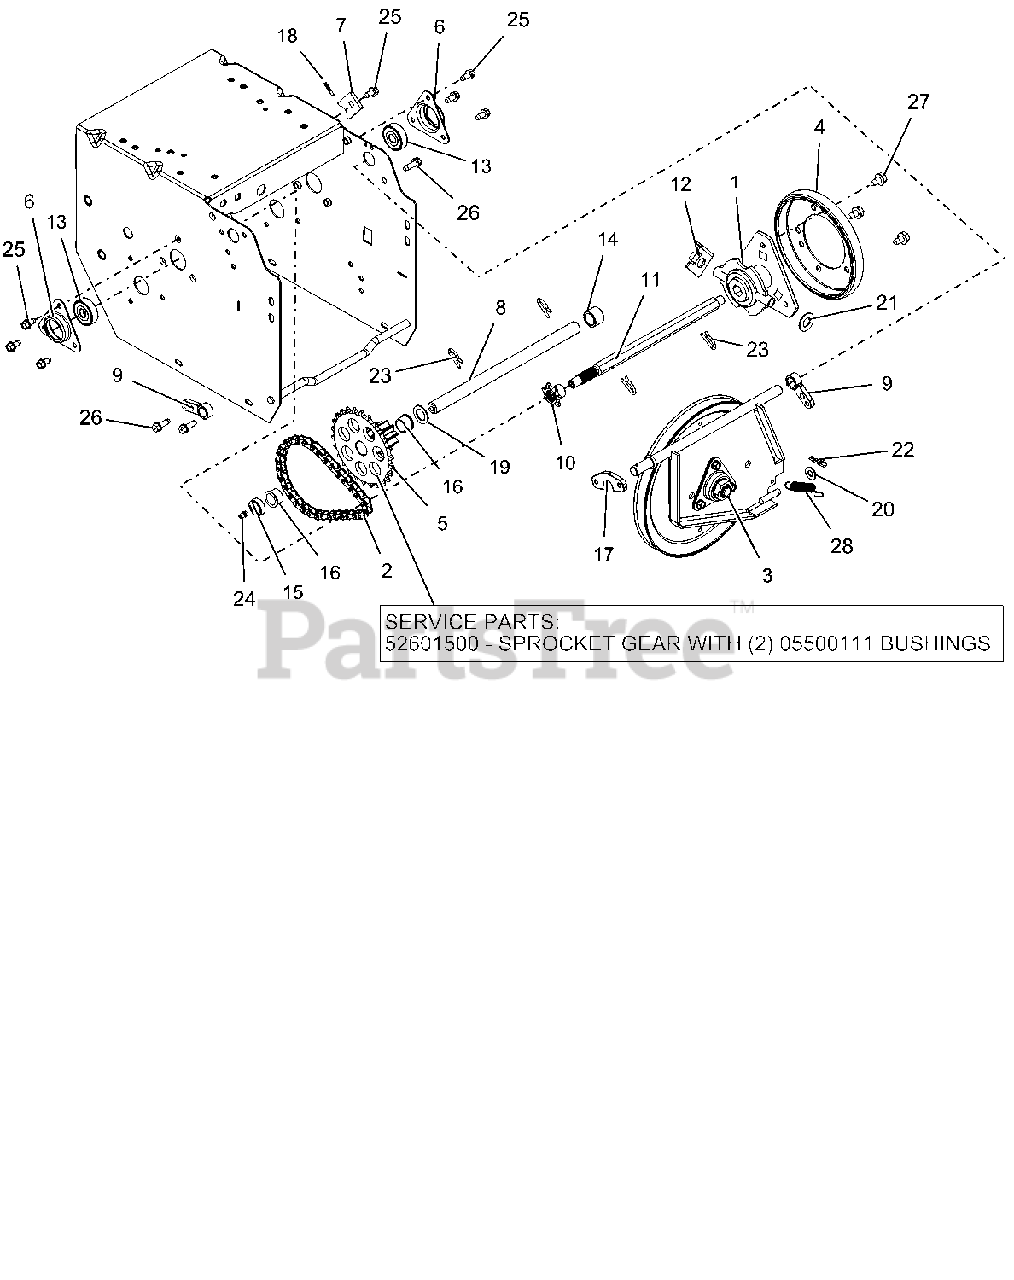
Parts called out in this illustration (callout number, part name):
1	CARRIER, DRIVE DISK
2	CHAIN - #41, 32 PITCHES
3	PLATE, SWING - ASSEMBLY
4	FRICTION, DISC
5	BSHG-FLG .625X.750X.500X.875
5	PINION & SPROCKET
5	PINION & SPROCKET W/BUSHINGS
6	FLANGE, BEARING
7	TAB, ANTI ROTATION
8	SHAFT, PINION
9	SUPPORT BUSHING, SWING GATE
10	SPROCKET, PINION 7T W/SPLINE
11	SHAFT, HEX W/SPLINE
12	BRACKET, FORMED - SHIFT FORK
13	BRG-BALL .437X1.375X.437
14	SPACER, .635X.880X.611
15	BSHG-SLV, .635X.880X.305
16	BSHG-FLG .625X.750X.500X.875
17	SPACER, SWING GATE
18	@PIN-GRV .125X1.00 TP E ALLOY
19	WSHR-FL-STL .630X1.005X.062 YZ
20	@WSHR-FL-STL.344X.688X.065YWZC
21	WSHR-FL-STL .505X1.00X.062YWZC
22	PIN-HAIR INT .08X.18X1.18 YWZC
23	PIN, SPRING CLIP
24	ZERK,FITTING .25X.125 DRIVE IN
25	SCR-TAP .25-20X.50 HWH TR YWZ
26	SCR-TAP-PM .25-20X.75 TR YWZ
27	@SCR-TAP .31-18X.50 HWH TR YWZ
28	SPRING, EXT. .043X.438X1.64
